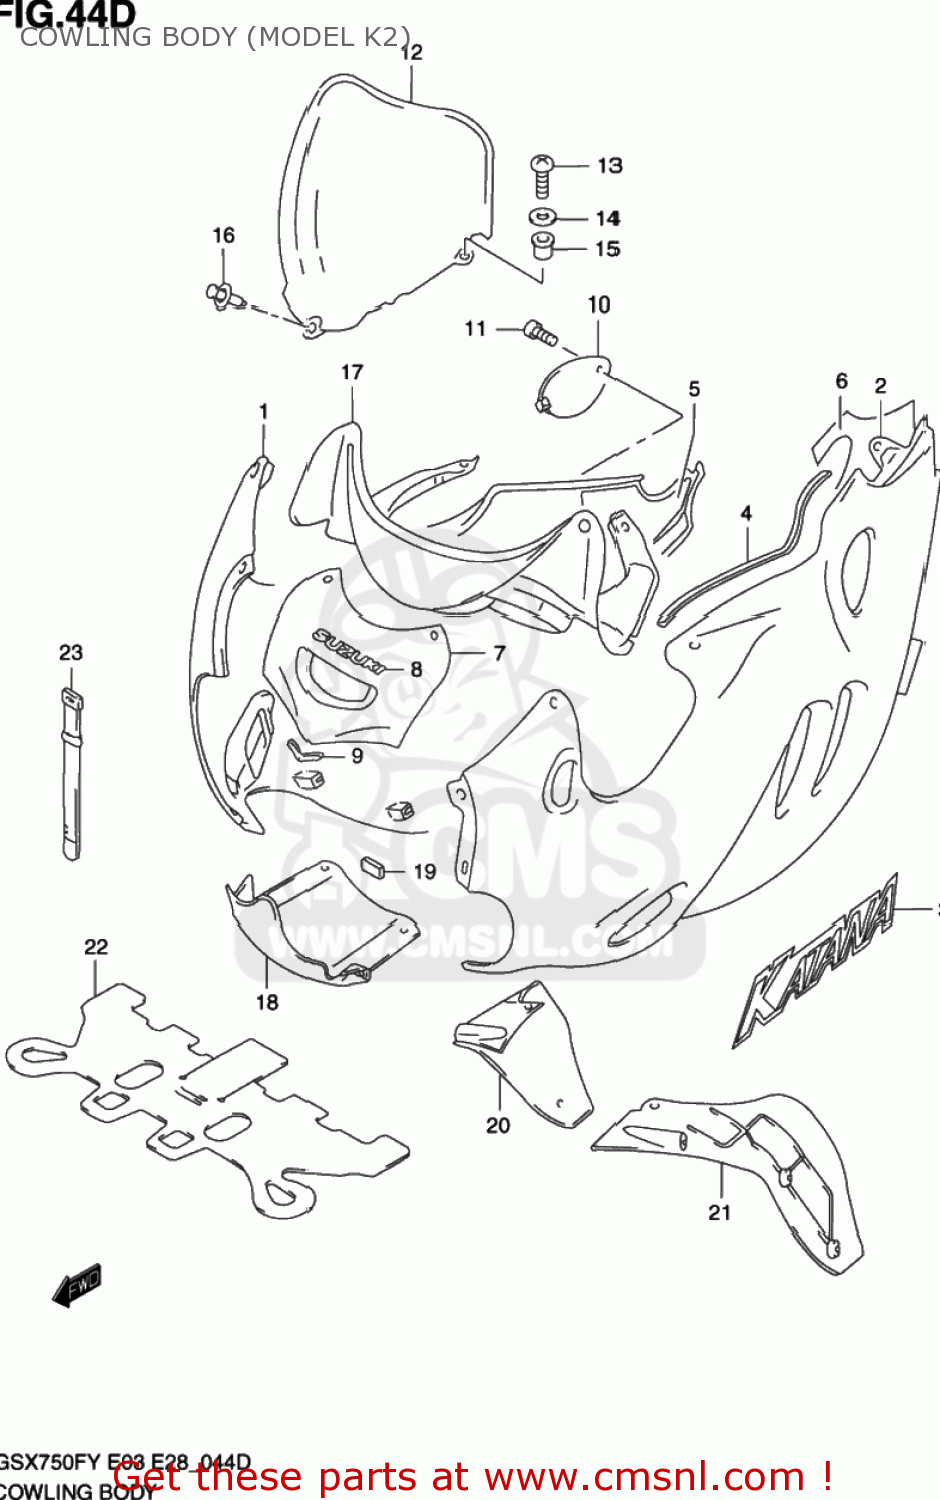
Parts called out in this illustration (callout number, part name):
1	COWLING ASSY,SIDE,R
2	COWLING ASSY,SIDE,L
3	EMBLEM,KATANA
4	MOLD,COWLING
5	SHIELD,COWLING COVER,R
6	SHIELD,COWLING COVER,L
7	PANEL,COWLING CTR UPR
8	EMBLEM,FR
9	CUSHION,CTR PANEL UPR
10	LID,OIL
11	SCREW(6X16)
12	WINDSCREEN
13	SCREW(5X14)
14	WASHER
15	NUT
16	CLIP(BLACK)
17	PANEL,METER
18	PANEL,COWLING CTR LWR
19	CUSHION,CENTER PANEL,LOWER
20	PANEL,COWLING INNER,R
21	PANEL,COWLING INNER,L
22	PLATE,AIR GUIDE
23	CLAMP(L:165)
